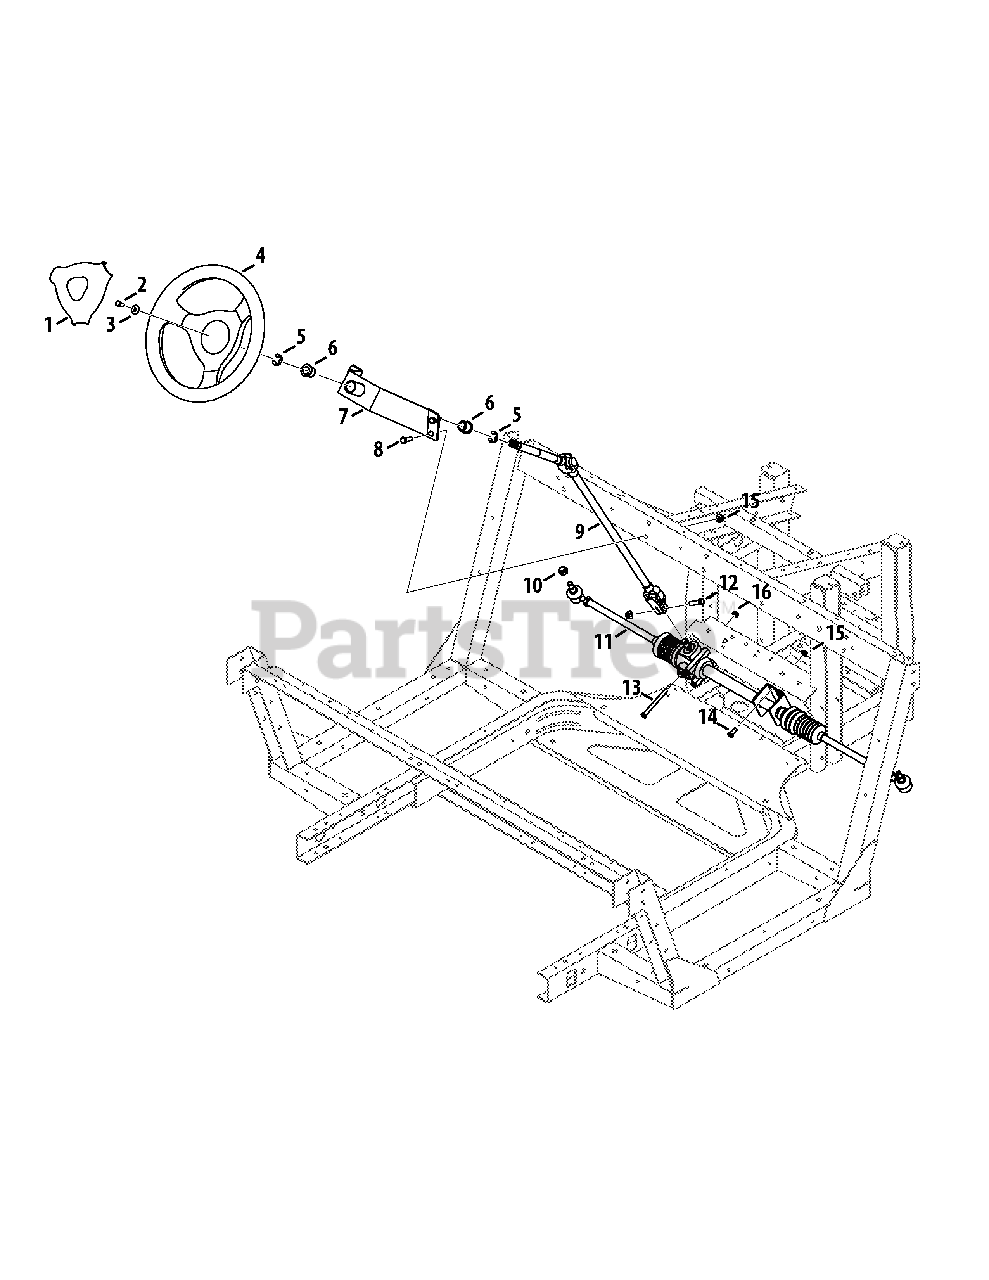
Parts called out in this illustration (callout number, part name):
1	Cover, Steering Wheel
2	Screw, 5/16-18 x 1.00, gr5, patch
3	Washer, bell, .340 x .872 x .060
4	Steering Wheel, Soft Grip 3 Spoke 5/8
5	Ring, e Type, .750
6	Flange Bearing, .754id x 1.00od x.925
7	Support Assembly, Steering Wheel
8	Screw, 3/8-16 x 1.00, gr5, std
9	Shaft, Steering
10	Nut, Nylock, m12 x 1.25
11	Steering Assembly
12	Screw, 3/8-16 x 1.25, gr5, std
13	Screw, 5/16-18 x 3.50, gr5, std
14	Screw, 5/16-18 x .75, gr5, std
15	Nut, Flange Lock, 3/8-16, Nylon
16	Nut, Flange Lock, 5/16-18
